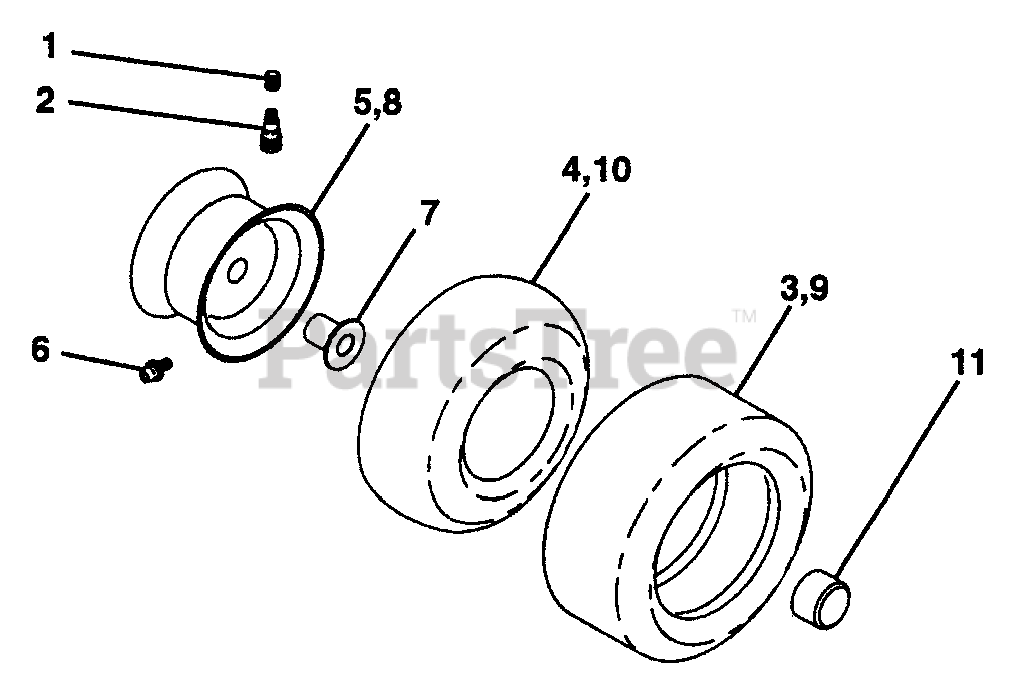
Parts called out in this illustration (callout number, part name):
1	Cap Valve Tire
2	Stem Valve
3	Tire F Ts 15 X 6 0 - 6 Service
4	Tube Front
5	Rim Asm 6"front Silver Service
6	Fitting Grease
7	Bearing Flange
8	Rim Asm 8"rear Silver Service
9	Tire R Ts 20x10-8 C Service
10	Tube Rear
11	Cap Axle Blk 1 50 X 1 00
